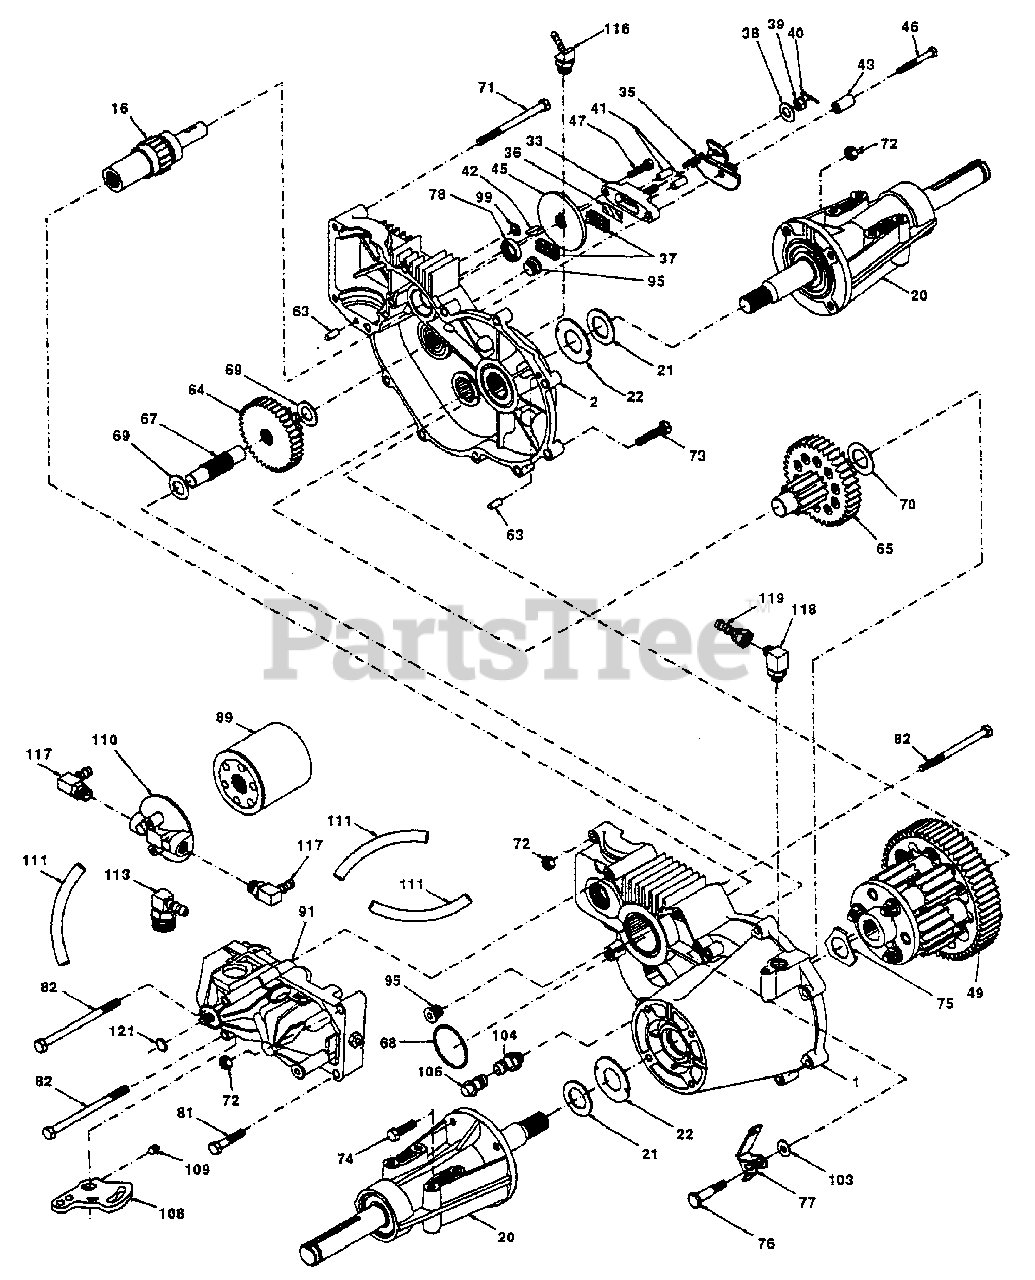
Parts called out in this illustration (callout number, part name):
1	Assembly, Lh Housing
2	Assembly, Rh Housing
16	Brake Shaft Assembly
20	Axle Mounting Horn Ass'y
21	Washer, 1.0 x 1.63 x .08
22	Washer, 1.0 x 2.06 x .09
33	Brake Yoke Assembly
36	Puck Plate
37	Brake Puck
38	Washer, 7/8od x 7/16 x .060
39	Castle Nut, 5/16-24
40	Cotter Pin
41	Brake Actuating Pin
42	Hi Pro Key
45	Brake Disc
46	Bolt, 1/4-20 X 1-1/2
47	Bolt, 1/4-20 X 1
49	Differential Assembly
64	14t-38t Reduction Gear
65	Final Drive Pinion Ass'y
67	Jack Shaft
69	Washer, 5/8 X 1-5/32
70	Washer, 7/8 X 1-1/2
71	Bolt, Hex 5/16-18 X 3.5
72	Hex Lock Nut, 5/16-18
73	Bolt, Hex 5/16-18 X 1-1/2
74	Hex Cap Screw, 5/16-18 X 1
75	Washer, Differential
76	Shoulder Bolt
77	Freewheel Actuating Arm
78	Oil Seal, .625 X 1.0 X .25
81	Bolt, Hex 5/16-18 X 1-3/4
82	Bolt, 5/16-18 X 4-1/2
89	Spin On Filter
91	Bdu-10l-118
95	Straight Thread Plug
99	Washer, 11/32 X 9/16
104	Cap-Vent Assembly
106	Fitting-O Ring Assembly
108	Control Arm
110	Filter Head
111	Hose, 5/16 X 12" Long
113	90° 7/8 Sae Fitting
116	45° 9/16 Sae Fitting
117	90° 9/16 Sae Fitting
118	90° Sae #6 Flare Male Fitting
119	90° Sae #6 Flare Female Fitting
121	Wire Retaining Ring
